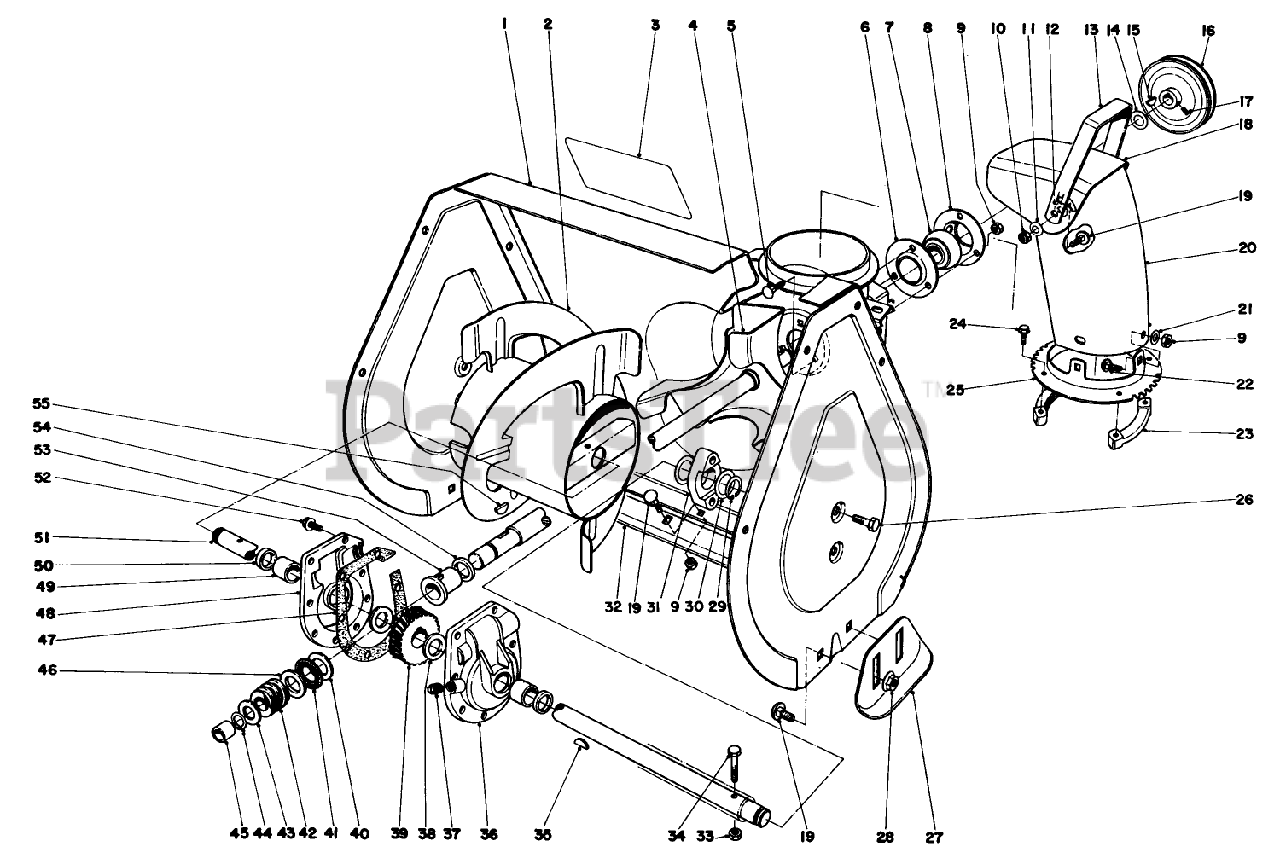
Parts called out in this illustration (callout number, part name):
1	Auger Housing
2	Auger R.H.
3	Decal-Warning
4	Shaft & Impeiler
5	BOLT-CARR
6	FLANGE-CUP, BEARING
7	Ball Bearing
8	FLANGE-CUP, BEARING
9	NUT-LOCK, NI
10	NUT-LOCK, CONE
11	WASHER-BELLEVILLE
12	WASHER-RUBBER
13	Handle Deflector
14	WASHER
15	KEY-WOODRUFF
16	PULLEY
17	SCREW-SET, SQH
18	Deflector
19	BOLT-CARR
20	Chute-Discharge
21	WASHER-PLAIN
22	SCREW-CARR
23	RING-CHUTE, RETAINER
24	SCREW-SPECIAL
25	Chute Ring
26	SCREW-HWHTF
27	Skid
28	NUT-HF
29	RING-RETAINING
30	WASHER
31	BEARING-AUGER
32	Blade-Scraper
33	NUT-LOCK, CONE
34	SCREW-HH
35	KEY-WOODRUFF
36	Gear Case L.H. (Incl. Ref. #49 & 50)
37	PLUG-PIPE, SQH
38	WASHER-THRUST
39	Gear
40	WASHER-THRUST
41	BEARING-THRUST
43	WASHER-THRUST
44	Ring-Snap
45	BUSHING
46	WASHER-THRUST
47	asket
48	Gear Case R.H. (Incl. Ref. #49 & 50)
49	BUSHING
50	SEAL-OIL
51	AUGER SHAFT
52	SCREW-TAPTITE
53	BUSHING-INPUT
54	RING-QUAD
55	KEY-WOODRUFF
